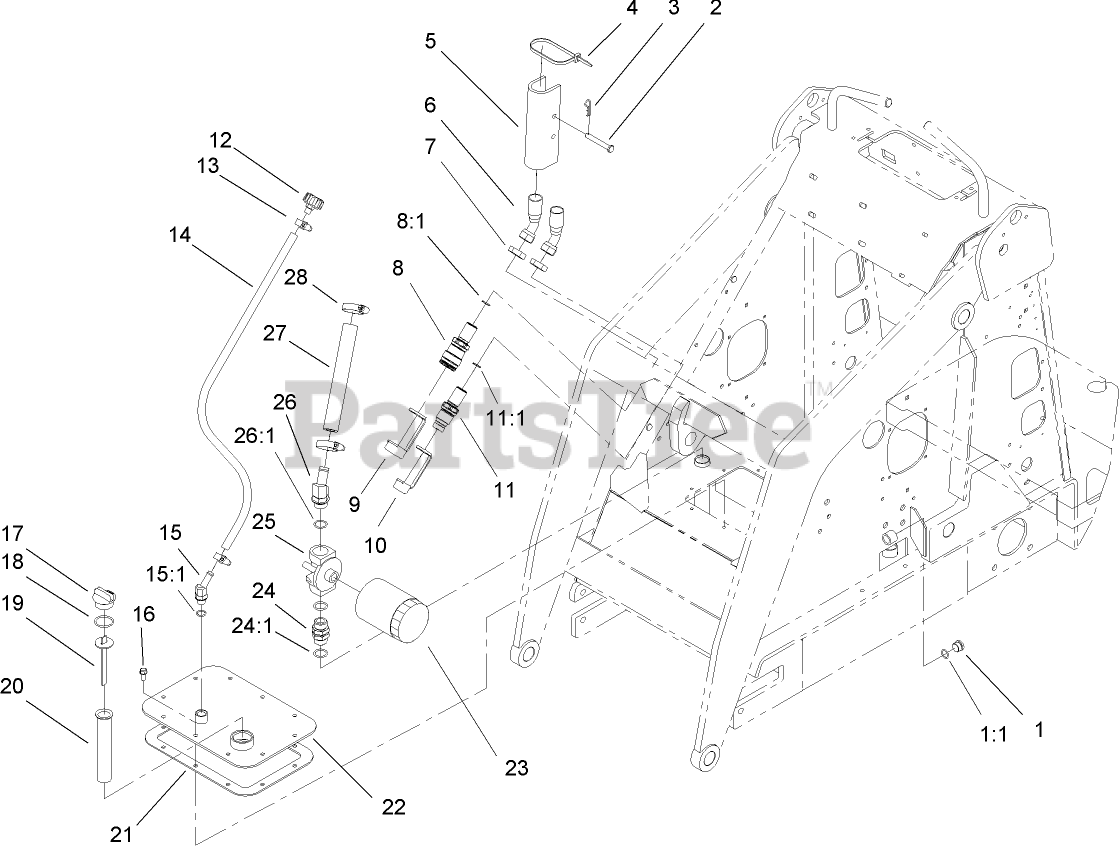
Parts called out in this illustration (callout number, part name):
1	PLUG-HEX
1:1	O-RING
2	PIN-CLEVIS
3	PIN-HAIR
4	TIE-CABLE
5	LOCK-CYLINDER
6	HOSE-HYD
7	NUT-LOCK, BULKHEAD
8	BULKHEAD COUPLER ASM
8:1	O-RING
9	CAP-DUST, COUPLER
10	CAP-DUST, NIPPLE
11	BULKHEAD NIPPLE ASM
11:1	O-RING
12	BREATHER
13	CLAMP-HOSE
14	HOSE-VENT
15	FITTING-HYD, 45 DEG
15:1	O-RING
16	SCREW
17	PLUG-PLASTIC
18	O-RING
19	DIPSTICK-OIL
20	FILTER-SCREEN
21	GASKET-COVER
22	COVER
23	FILTER-OIL, TRANSMISSION
24	FITTING-THREAD, STRAIGHT
24:1	O-RING
25	HEAD-FILTER
26	ELBOW-45 DEG
26:1	O-RING
27	HOSE-SUCTION, HYD
28	CLAMP-HOSE
